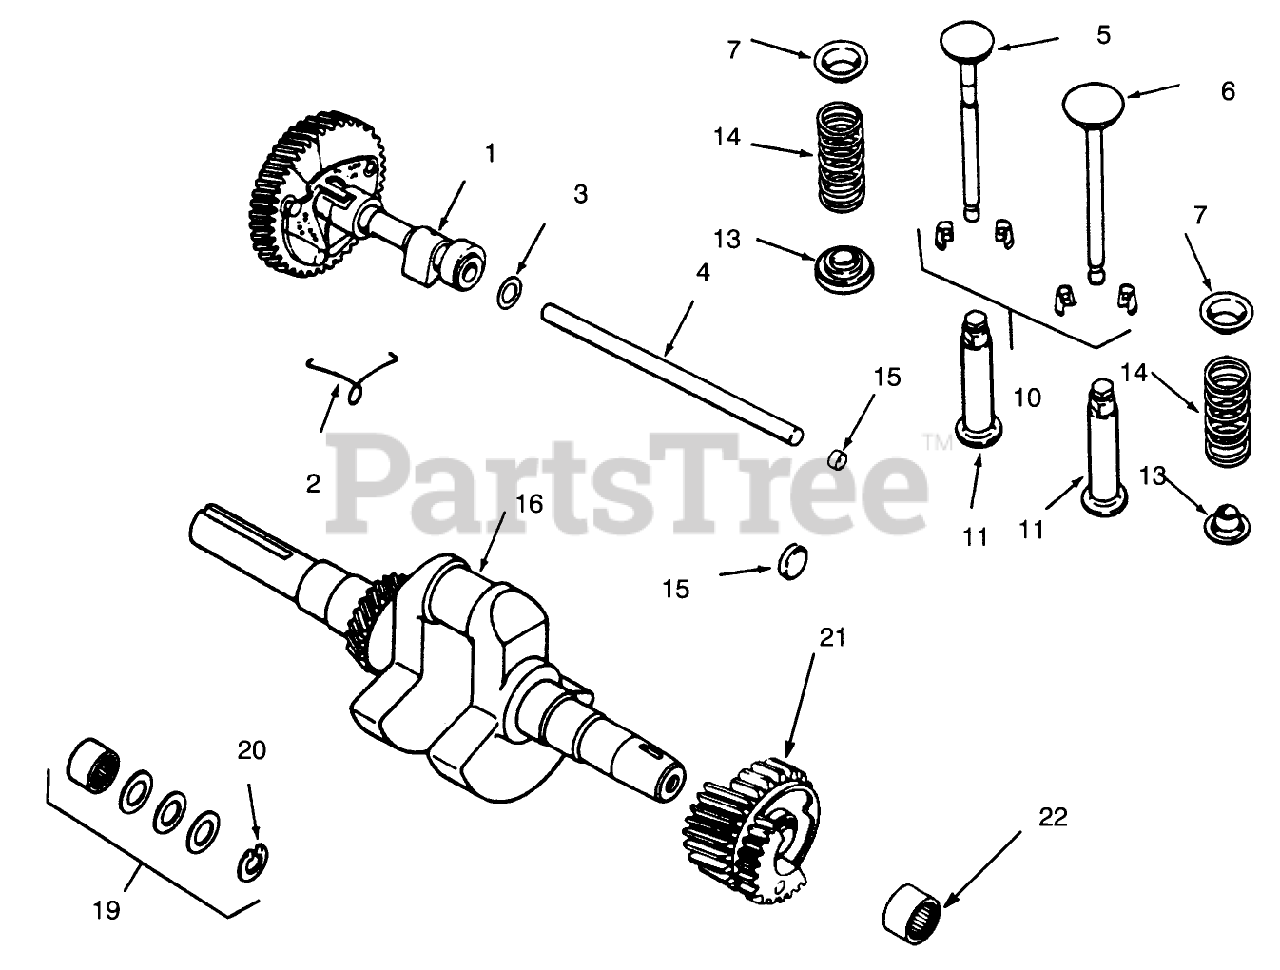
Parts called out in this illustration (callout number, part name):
1	KOHLER 47-010-11
2	KOHLER 47-089-01
3	KOHLER 275066
4	KOHLER 47-380-09
5	KOHLER 237672
6	KOHLER 235582
7	KOHLER 235011
10	KOHLER 41-755-10
11	KOHLER D-235327
13	KOHLER 52-413-01
14	KOHLER 235168
15	KOHLER X-702-3
16	KOHLER 45-142-21
19	KOHLER 47-755-01
20	KOHLER X-269-34
21	KOHLER 45-043-03
22	KOHLER 47-030-01
